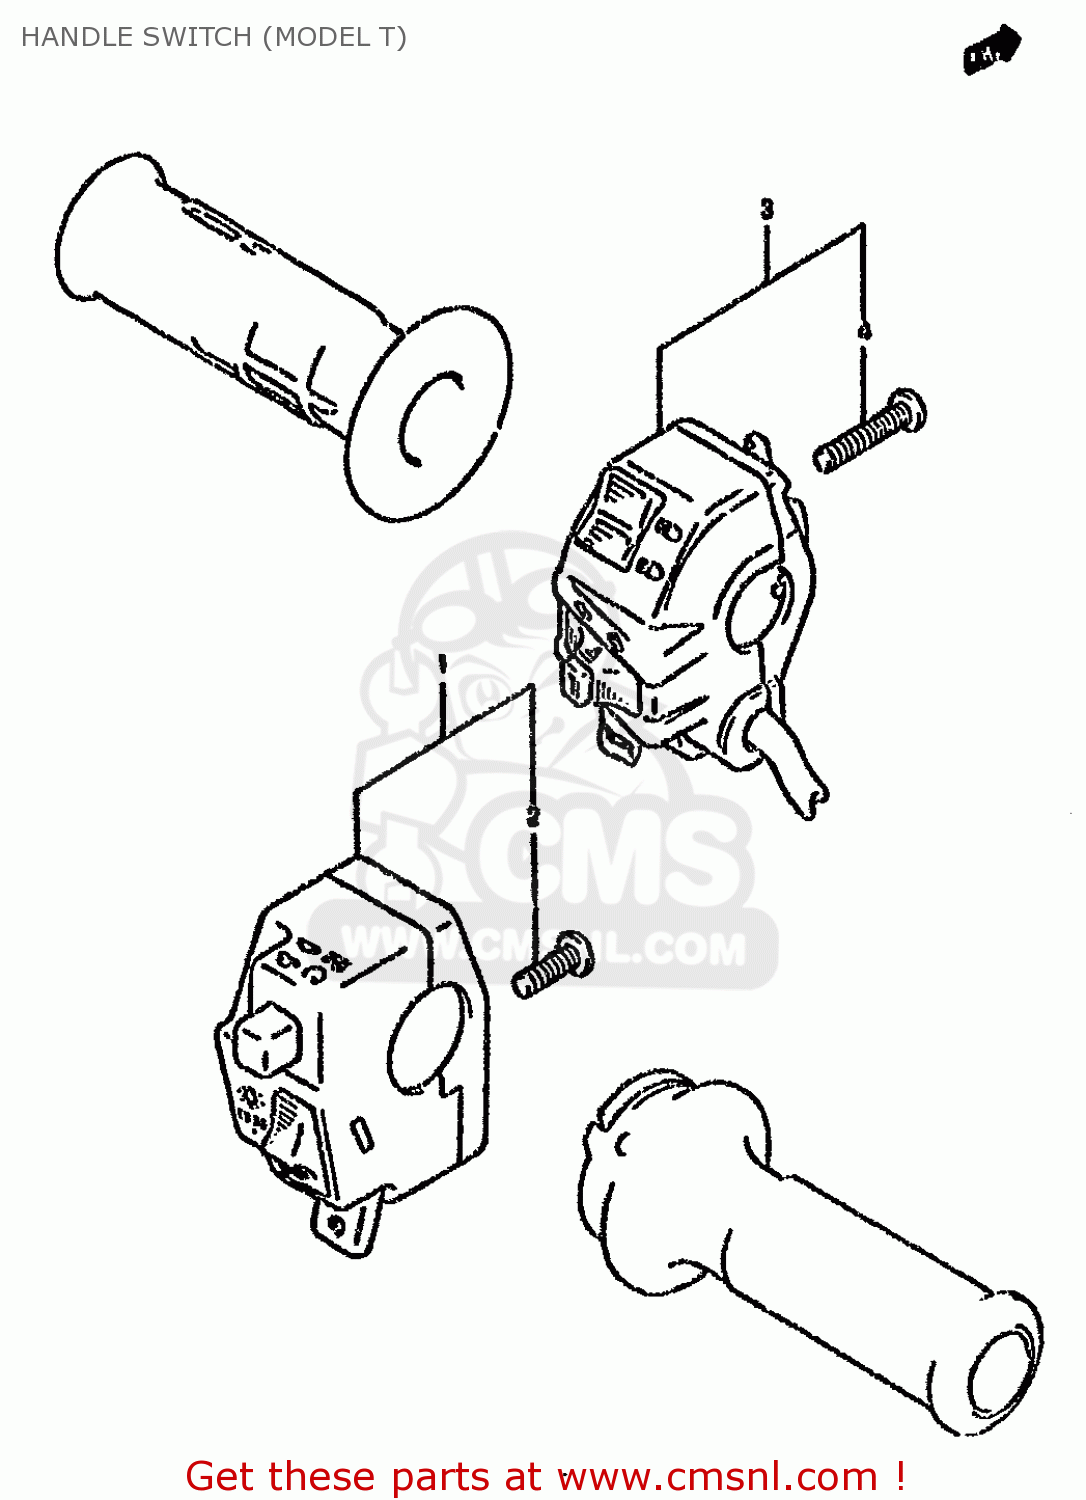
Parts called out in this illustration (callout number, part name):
1	SWITCH ASSY,HANDLE,R
2	SCREW
3	SWITCH ASSY,HANDLE,L
4	SCREW
